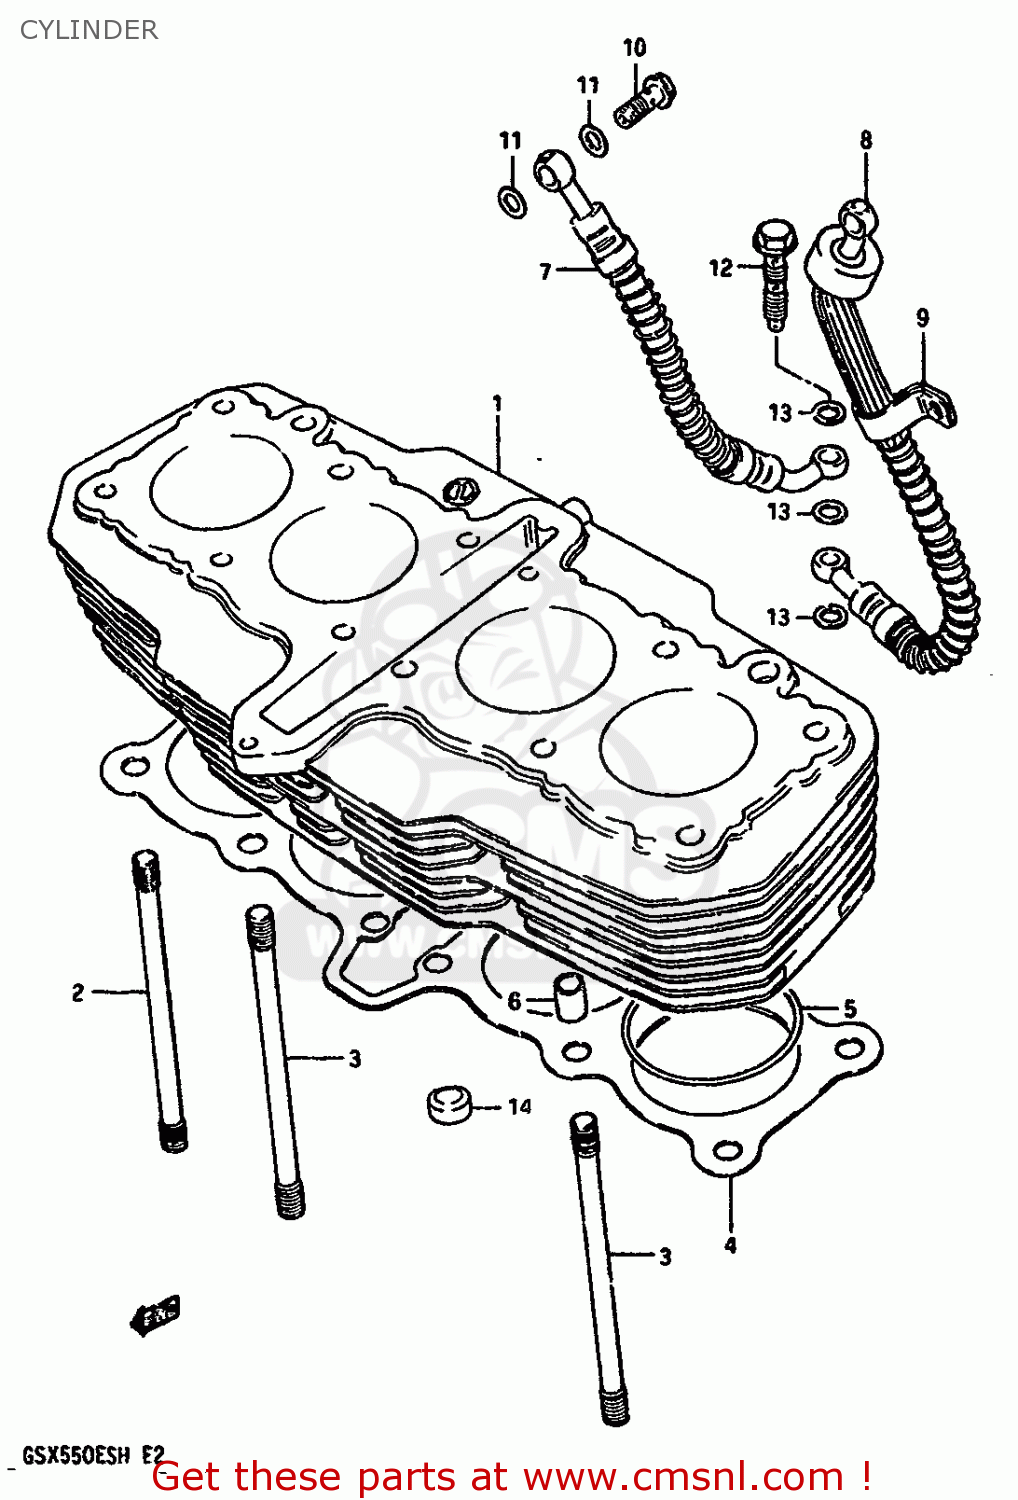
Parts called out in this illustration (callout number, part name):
1	CYLINDER
2	STUD
3	BOLT,STUD
4	GASKET,CYLINDER (MCA)
5	O RING(D:2,ID:61)
6	PIN
7	HOSE,OIL CRANKCASE,R
8	HOSE,OIL CRANKCASE,L
9	CLAMP,OIL HOSE CRANKCASE
10	BOLT UNION
11	GASKET 8.2X14X1 (NAS)
12	BOLT,OIL PIPE
13	WASHER(10X15X1.5)
14	PAD,CYLINDER HEAD
